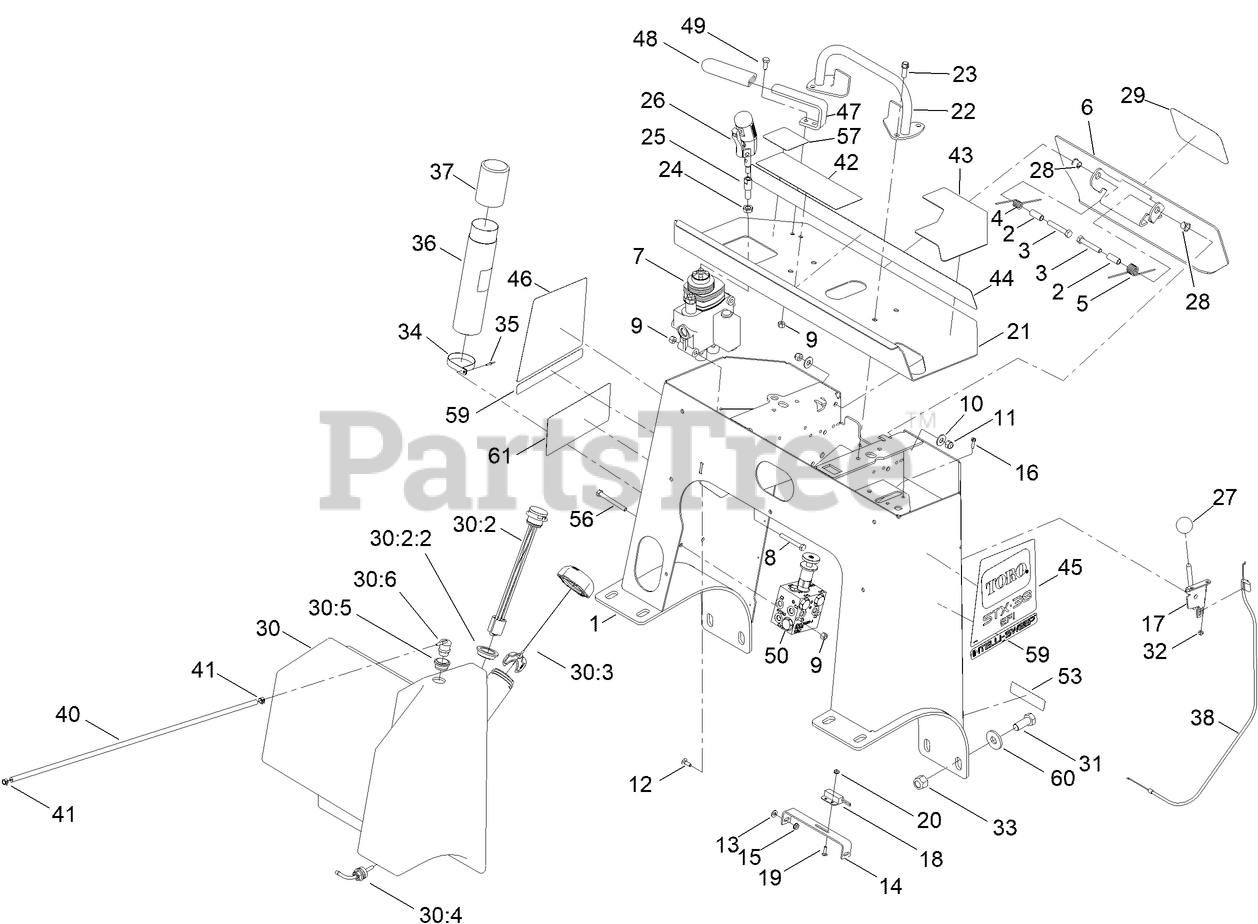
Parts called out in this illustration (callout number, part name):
2	SPACER-SPRING
3	SCREW-HH
4	SPRING-TORSION, LH
5	SPRING-TORSION, RH
6	PLATE-BACKUP
7	HYD VALVE ASM
8	SCREW-HH
9	NUT-LOCK, NI
10	WASHER-FLAT
11	NUT-LOCK, NI
12	BOLT-CARR
13	WASHER-FLAT
14	PLATE-SWITCH
15	NUT-KEPS
16	SCREW-HWH
17	LEVER-CONTROL
18	SWITCH-PROXIMITY
19	SCREW-CARR
20	NUT-KEPS
21	PANEL-CONTROL
22	BAR-REFERENCE
23	SCREW-TAPTITE
25	ADAPTER-HANDLE
26	TWO BUTTON HANDLE GRIP ASM
28	BUSHING-NYLINER
30	FUEL TANK ASM
30:2	GAUGE ASM
30:4	FITTING-FUEL, BULKHEAD
30:5	GROMMET
30:6	VALVE-VENT, FUEL
31	SCREW-HH
32	NUT-LOCK, NI
33	NUT-LOCK, NI
34	CLAMP-R
35	RIVET-POP
36	TUBE-MANUAL
37	CAP-HOUSING
38	CABLE-CONTROL
40	HOSE-FUEL
41	CLAMP-HOSE
42	DECAL-WARNING
43	DECAL-CONSOLE, LH
44	DECAL-CONSOLE, RH
45	DECAL-LOGO,LH
46	DECAL-LOGO,RH
47	BAR-ARM REST
48	GRIP-LEVER
49	SCREW-HH
50	SWEEP MANIFOLD ASM
53	DECAL-ARRESTOR, SPARK
56	SCREW-HH
57	DECAL-JOYSTICK
59	DECAL-INTELLISWEEP
60	WASHER-HARDENED
61	DECAL - SERVICE
